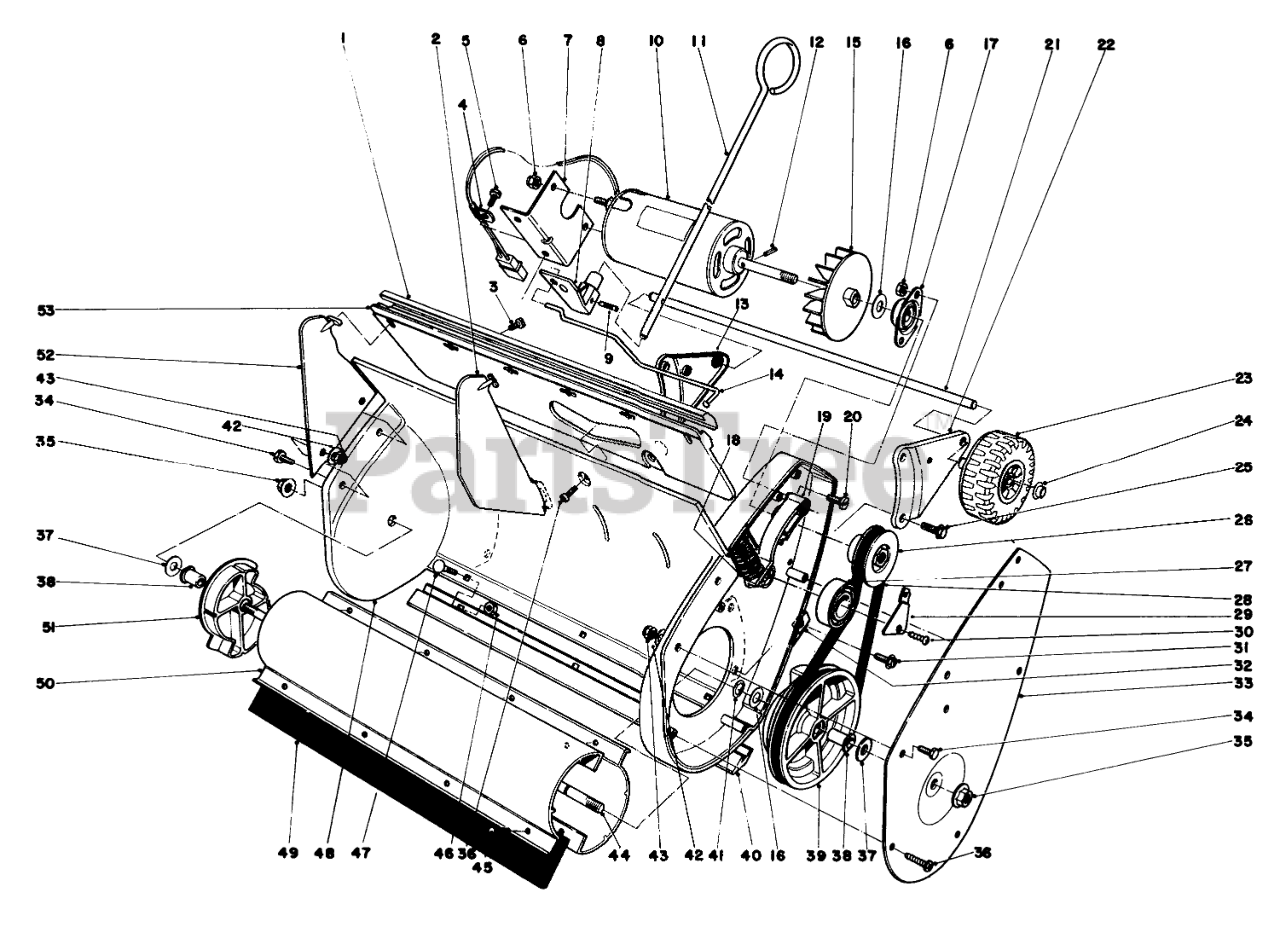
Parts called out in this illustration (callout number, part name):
1	MOULDING
2	VANE INNER
3	10-16 X 3/8 THDG SCREW
4	CLIP-CLOSED, INSULATED
6	NUT-LOCK, NI
7	MOUNTING BRKT B
8	VANE ADJ BRKT
9	GROOVE PIN
10	Motor
11	VANE ADJ ROD
12	SPRING PIN
13	Bracket R.H.
14	Linkage Vane Adjustment
16	WASHER-THRUST
17	SIDE FLANGE BRG
18	IDLER COMP. SPRING
19	IDLER ARM
20	Screw
21	AXLE SHAFT
22	Wheel Bracket L.H.
23	S-120 WHEEL
24	PUSHNUT-CAP, WASHER
25	Screw
26	DRIVE PULLEY
27	BEARING-BALL
29	IDLER PULLEY RETAINER
30	#8 X .625" PHILPS PAN H
31	SCREW-HWHTF
32	NUT-TYPE J
33	Cover-Belt Case
34	SCREW-HWH
35	NUT-HF
36	Screw
37	THRUST WASHER (THICK)
38	BUSHING ROTOR
39	Pulley-Driven
40	SCRAPER-SERVICE
41	RING-RETAINING
42	Washer
43	NUT-LOCK, NI
44	ROTOR SHAFT
45	Screw
46	NUT-KEPS
47	SCREW-CARR
48	Housing
49	Blade-Rotor
50	ROTOR
51	END CAP ROTOR
52	VANE OUTSIDE
53	Vane Mount
